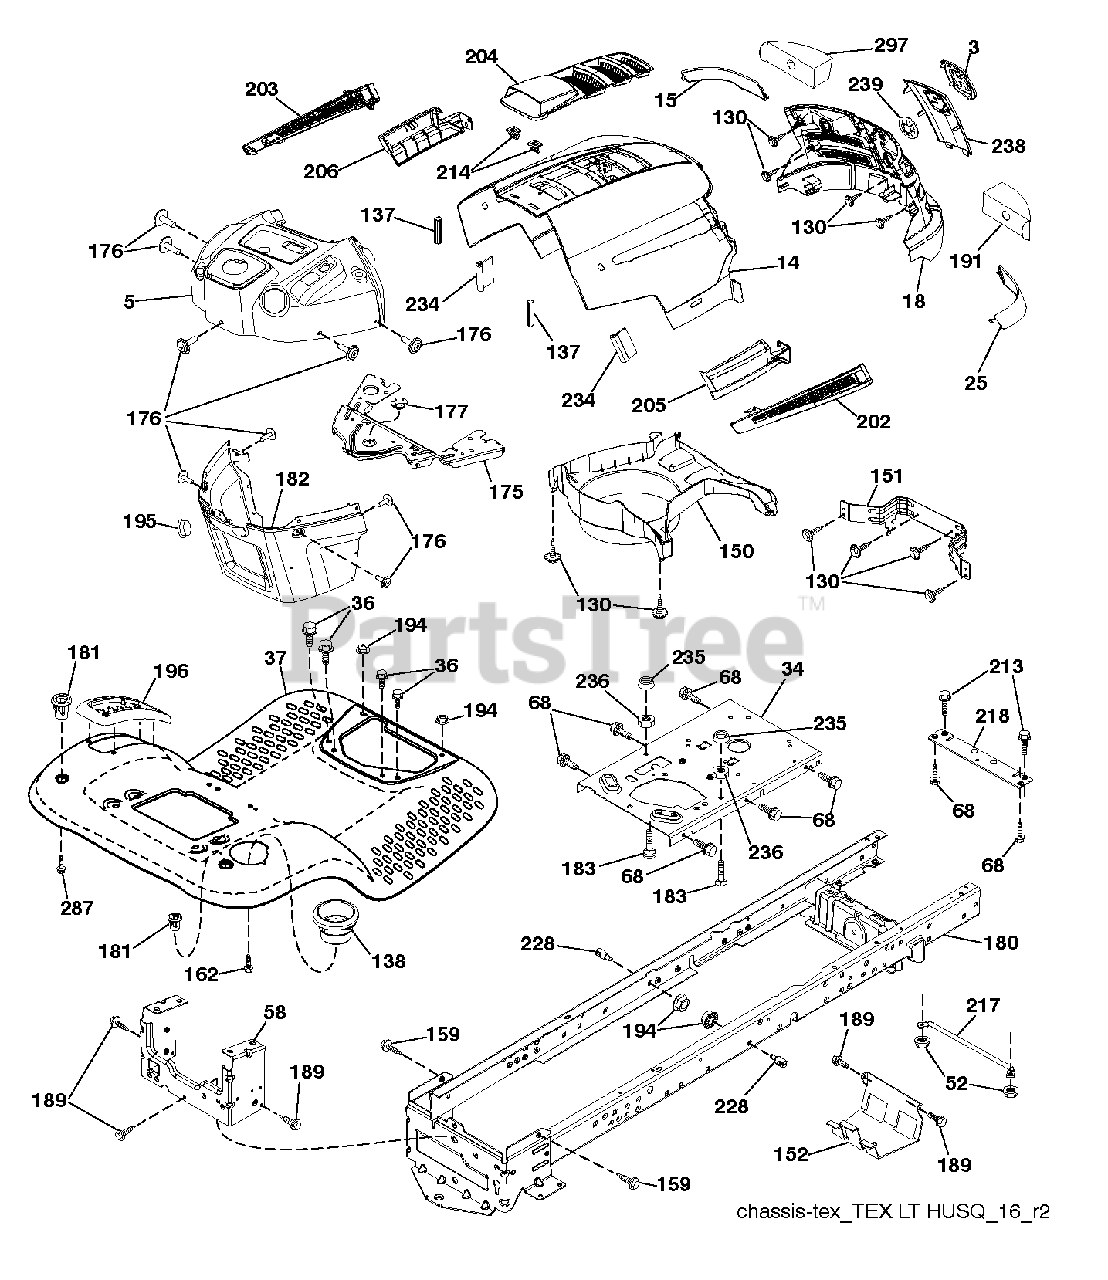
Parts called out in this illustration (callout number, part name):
3	LOGO.HUSQ.GT.LT.CROWN.H
5	SUBASM.DASH.UPPER.W/BUMPER
14	HOOD.HUSQVARNA.LT.ORANGE
15	LENS RH
18	GRILLE.SVC.HUSQVARNA.GREY
25	LENS LH
34	PLATE.ENGINE.WELDED.CHASSIS
36	SCREW 5/16"
37	FENDER.TLT.FS.W/CUPHLD.ORANGE
52	LOCKNUT
58	DRAWBAR UPPER 2PC SMALL FENDER
68	SCREW LT
130	SCREW.#10 X 0.750.BOS
137	BUMPER DASH
138	HOLDER.CUP.LT.GREY
151	BRACKET PIVOT
152	SHIELD.BROWNING.W/TEX
159	SCREW, 3/8-16X3/4
162	SCREW.HI-LO.CONSOLE
175	CROSSMEMBER
176	SCREW.#10-24X5/8.RN.QU
177	BUSHING STEERING
180	CHASS.WLDMNT.TL.12GA/2P.48/54
181	BUSHING.MNT.FEND.CRGO.TEX.49
182	DASH.LOWER.PREDATOR LT
183	BOLT.5/16-18X1-1/4 FULL THD
189	SCREW
191	INSERT.REFLECTIVE.RH.
194	NUT LOCK HEX FLANGE 5/16-18
195	PLUG.TEX.DASH.SVC.MINDER.GREY
196	DECKLFT.CONSOL FULL ASSM GREY
202	VENT.SIDE.HUSQVARNA.LT.RT
203	VENT.SIDE.HUSQVARNA.LT.LFT
204	SUBASM.TOP.VENT.HUSQ.LT
205	SKIRT.SIDE.HUSQVARNA.LT.RT
206	SKIRT.SIDE.HUSQVARNA.LT.LEFT
213	BOLT
214	CLIP.RETAINER.TINNER.
217	ROD.PIVOT.HOOD
218	X-PIECE.HOOD.STOP.NON/
228	STUD.FASTNER.W/ANTI-ROTATE
234	BUMPER.HOOD.TEX.HUSQVARNA
235	SPACER FENDER
236	NUT.CENTERLOCK.5/16-
238	TRIM.HUSQ LT.668
287	SCREW 1/4X20
297	INSERT REFLECTIVE
